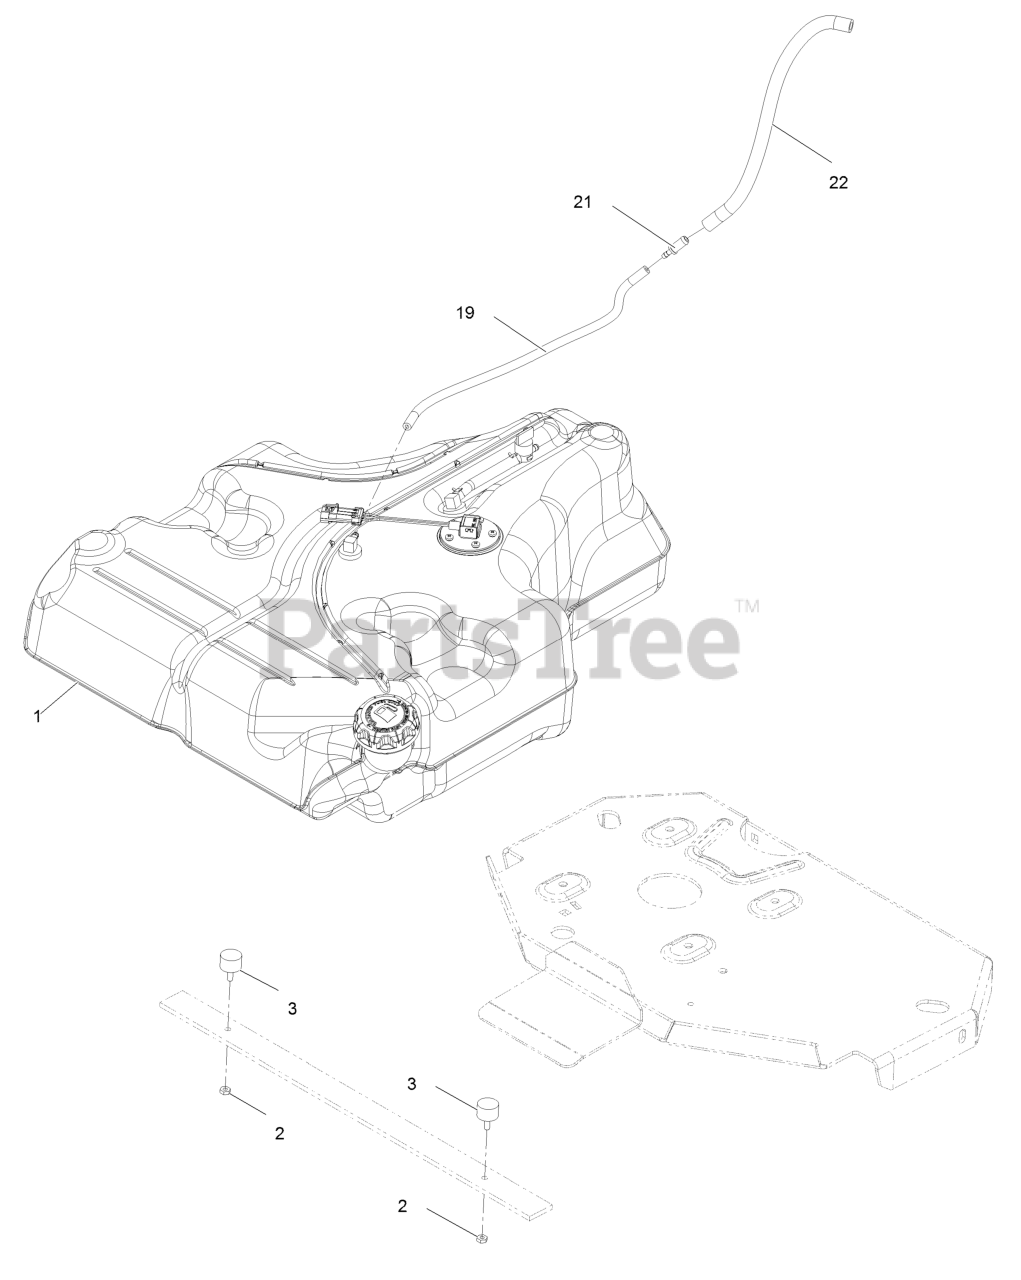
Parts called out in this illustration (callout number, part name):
1	FUEL TANK ASM
2	NUT-JAM
19	HOSE-FUEL
21	FITTING-STRAIGHT
22	HOSE-FUEL
